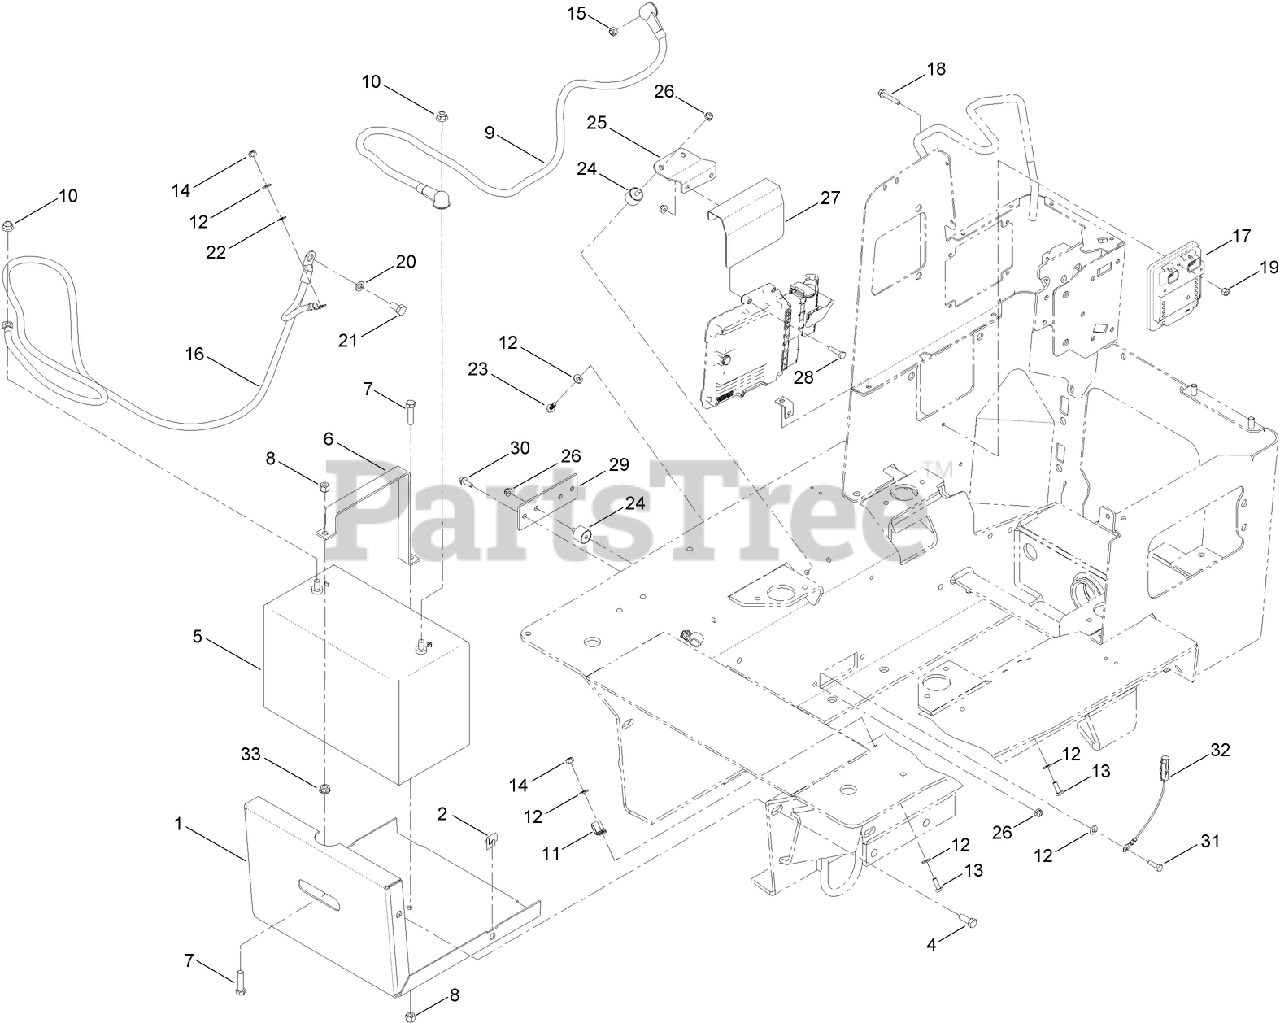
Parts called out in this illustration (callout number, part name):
1	RACK-BATTERY
2	NUT-SPRING
4	SCREW-HHF
5	BATTERY (1000CCA, WET)
6	BRACKET-BATTERY
7	SCREW-HH
8	NUT-HEX
9	CABLE-BATTERY, POSITIVE
10	NUT-HF, NI
11	CLAMP-CABLE
12	WASHER-FLAT
13	SCREW-HH
14	NUT-LOCK, CONE
15	NUT-LOCK, NI
16	CABLE-BATTERY, NEGATIVE
17	MODULE-CONTROL, STANDARD
18	SCREW-HHF
19	NUT-LOCK, NI
20	WASHER-LOCK
21	SCREW-HH
22	WASHER-LOCK
23	SCREW-HHF
24	MOUNT-CYLINDRICAL
25	PLATE-E C U
26	NUT-HF
27	COVER-DRIP
28	SCREW-HH
29	PLATE-E C U
30	SCREW-HHF
31	SCREW-HH
32	HARNESS-WIRE
33	NUT-HHF, WHIZ
